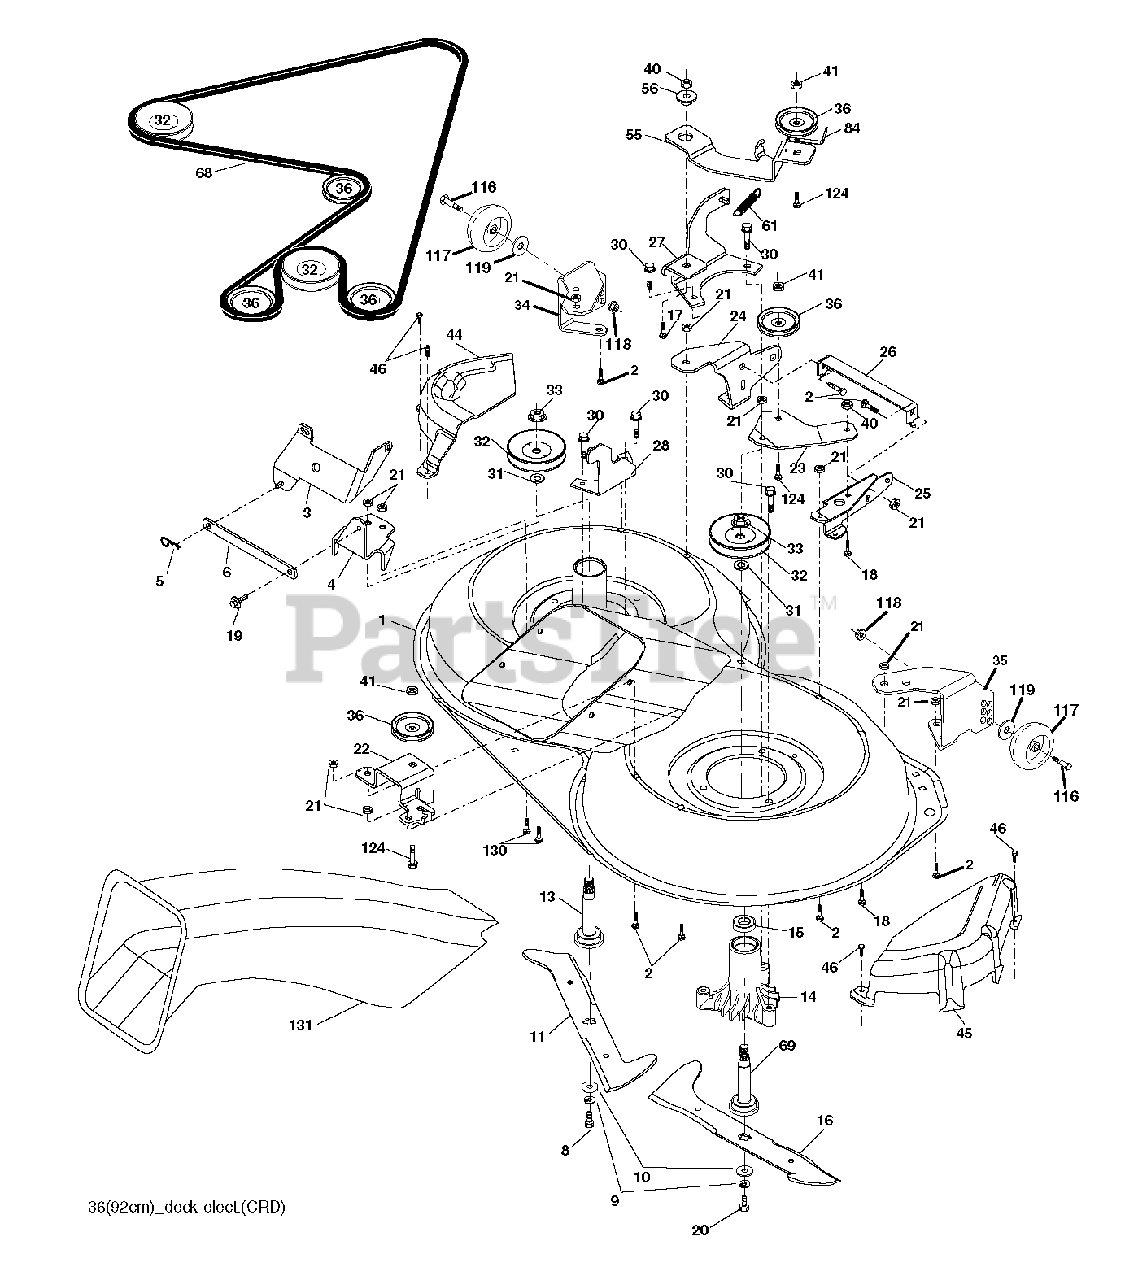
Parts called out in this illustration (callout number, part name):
2	BOLT
3	BRACKET
5	RETAINER-SPRNG RB
6	BAR SWAY
9	LOCKWASHER
10	WASHER.BLADE
13	SHAFT ASM VENT
14	HSG MANDREL
17	BOLT.3/8-14X1.25
19	BOLT SHD 5/16-18
21	LOCKNUT
24	BRACKET
25	BRACKET
28	BRACKET
30	SCREW, WASHER HEAD
31	WASHER.SPACER.MANDREL
33	NUT.FLANGE.LOCK.TOP
36	PULLEY.IDLER.4.25
40	LOCKNUT
41	NUT LOCK FLG 3/8-16 UNC
45	MANDREL COVER
46	SCREW.1/4-20X5/8
56	SPACER.RETAINER.MOWER
69	SHAFT.ASM.W/LWR.BRG.RH.THREAD
84	KEEPER, BELT IDLER
116	BOLT.SHOULDER.3/8-16X3-5/8
117	WHEEL. GUAGE RALLY
118	NUT LOCK FLG 3/8-16 UNC
124	BOLT.3/8-16X1.50
131	CHUTE BAGGER
